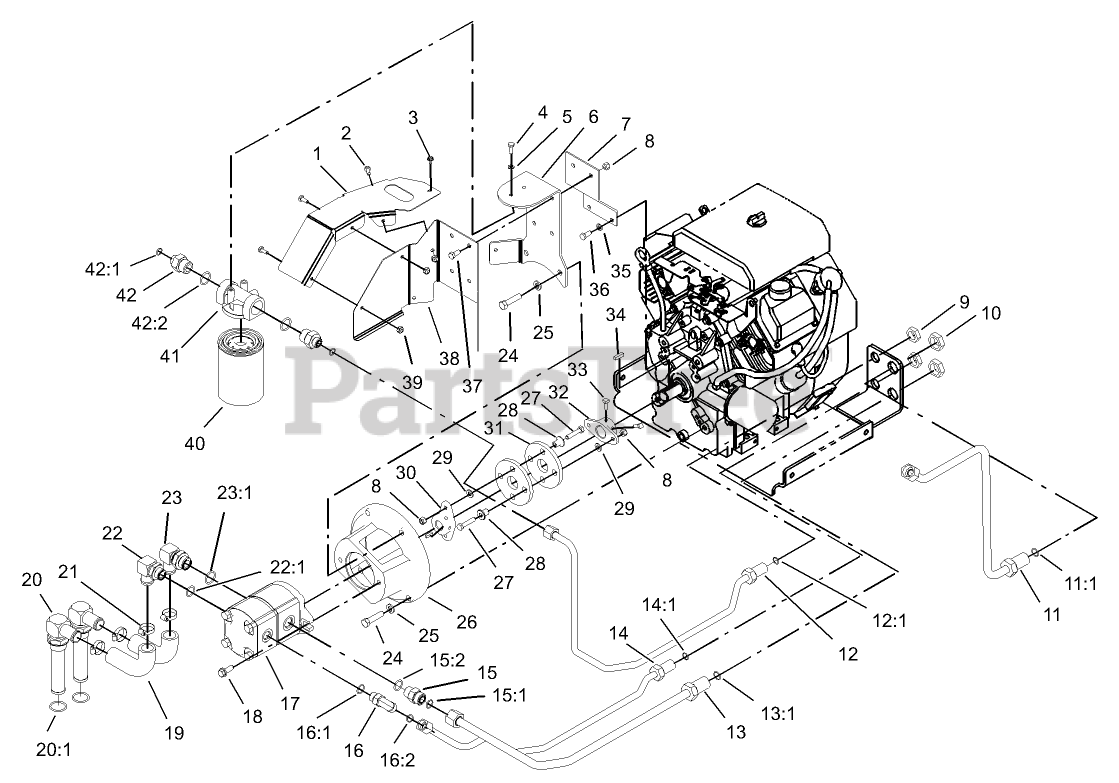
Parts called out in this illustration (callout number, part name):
1	SHIELD-HEAT
2	SCREW-HH
3	SCREW
4	SCREW-HH
5	WASHER-LOCK
6	BRACKET-SUPPORT, OIL FILTER
7	BRACKET-SUPPORT, OIL FILTER
8	NUT-LOCK, NI
9	NUT-BULKHEAD
10	NUT-LOCK, BULKHEAD
11	HYD TUBE ASM
11:1	O-RING
12	HYD TUBE ASM
12:1	O-RING
13	HYD TUBE ASM
13:1	O-RING
14	HYD TUBE ASM
14:1	O-RING
15	FITTING-STRAIGHT
15:1	O-RING
15:2	O-RING
16	FITTING-ELBOW-90 DEG
16:1	O-RING
16:2	O-RING
17	PUMP-GEAR, HYD
18	SCREW-HHF
19	HOSE-SUCTION, FORMED
20	STRAINER FITTING ASM
20:1	O-RING
21	CLAMP-HOSE
22	STEM-HOSE, 90 DEG
22:1	O-RING
23	FITTING-HYD, 90 DEG
23:1	O-RING
24	SCREW-HH
25	WASHER-LOCK
26	Mount-Pump
27	SCREW-HH
28	SPACER
29	WASHER-PLAIN
30	HUB-PUMP
31	COUPLING-RUBBER
32	HUB-ENGINE
33	SCREW-SQH
34	KEY-SQUARE
35	WASHER-LOCK
36	SCREW-HH
37	SCREW-HH
38	SHIELD-HEAT, FILTER
39	NUT-LOCK, NI
40	FILTER-OIL
41	HEAD-FILTER
42	FITTING-STR
42:1	O-RING
42:2	O-RING
